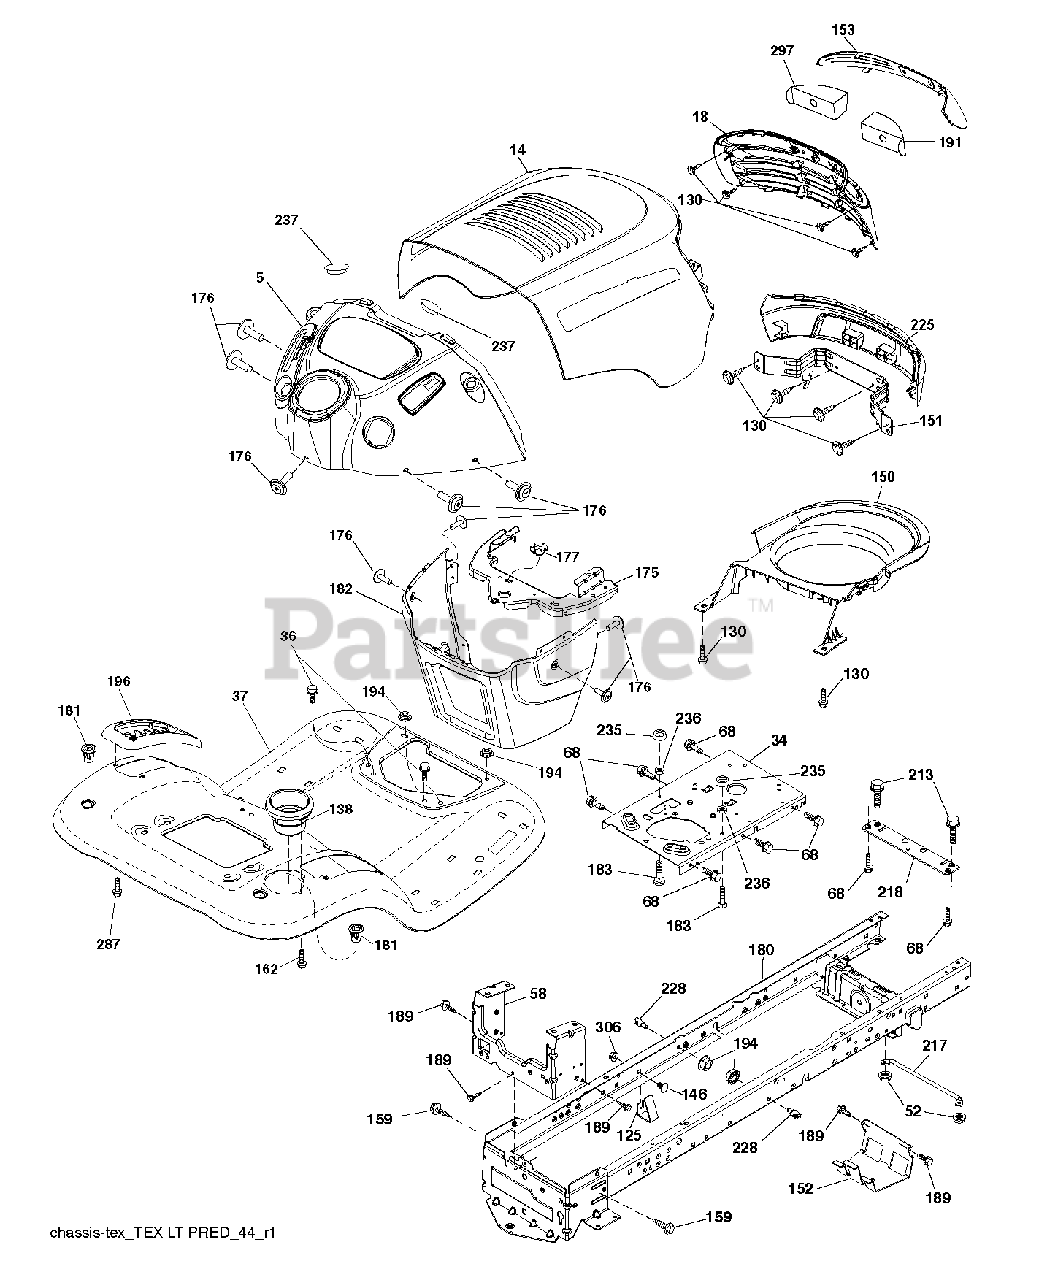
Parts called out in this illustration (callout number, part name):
5	DASH.PRED.LT.CC.ICY.SRVMDR.BLK
14	HOOD.PREDATR.LT.BLUE.DIXON
18	GRILLE SVC.PPRED.LT.DIXON.BLCK
34	PLATE.ENGINE.WELDED.CHASSIS
36	SCREW 5/16"
37	FENDER.TLT.W/CPH.BLUE
52	LOCKNUT
58	DRAWBAR UPPER 2PC SMALL FENDER
68	SCREW LT
125	CLIP.FUEL.LINE
130	SCREW.#10 X 0.750.BOS (2 2)
138	CUPHOLDER.TL.TEX.BLACK
146	BOLT.RDHD.SHT.SQNK.3/8-16X5/8
150	DUCT.AIR.TOP.VENT.PREDATOR.LT
151	BRACKET.PIVOT.ALPHA.LT
152	SHIELD.BROWNING.W/TEX
153	LENS.PREDATOR.LT
159	SCREW, 3/8-16X3/4
162	SCREW.HI-LO.CONSOLE
175	CROSSMEMBER
176	SCREW.#10-24X5/8.RN.QU
177	BUSHING STEERING
180	CHASS.WLDMNT.TL.12GA/2P.48/54
181	FEND/FTRST.PCH.CPH.NFW
182	DASH.LOWER.PREDATOR LT
183	BOLT.5/16-18X1-1/4 FULL THD
189	SCREW
191	INSERT.REFLECT.PREDATOR.LT.RH
194	NUT LOCK HEX FLANGE 5/16-18
196	CONSOLE.ASM.DECKLFT.BL/RBT.TLT
213	BOLT
217	ROD.PIVOT.HOOD
218	X-PIECE.HOOD.STOP.NON/
225	BUMPER.PREDATOR.LT.BLUE.DIXON
228	STUD.FASTNER.W/ANTI-ROTATE
235	SPACER FENDER
236	NUT.CENTERLOCK.5/16-
237	PLUG.MOUNT.CARGO.BLK
287	SCREW 1/4X20
297	REFLECTOR.INSERT.PRED.LH.LT
306	NUT LOCK FLG 3/8-16 UNC
